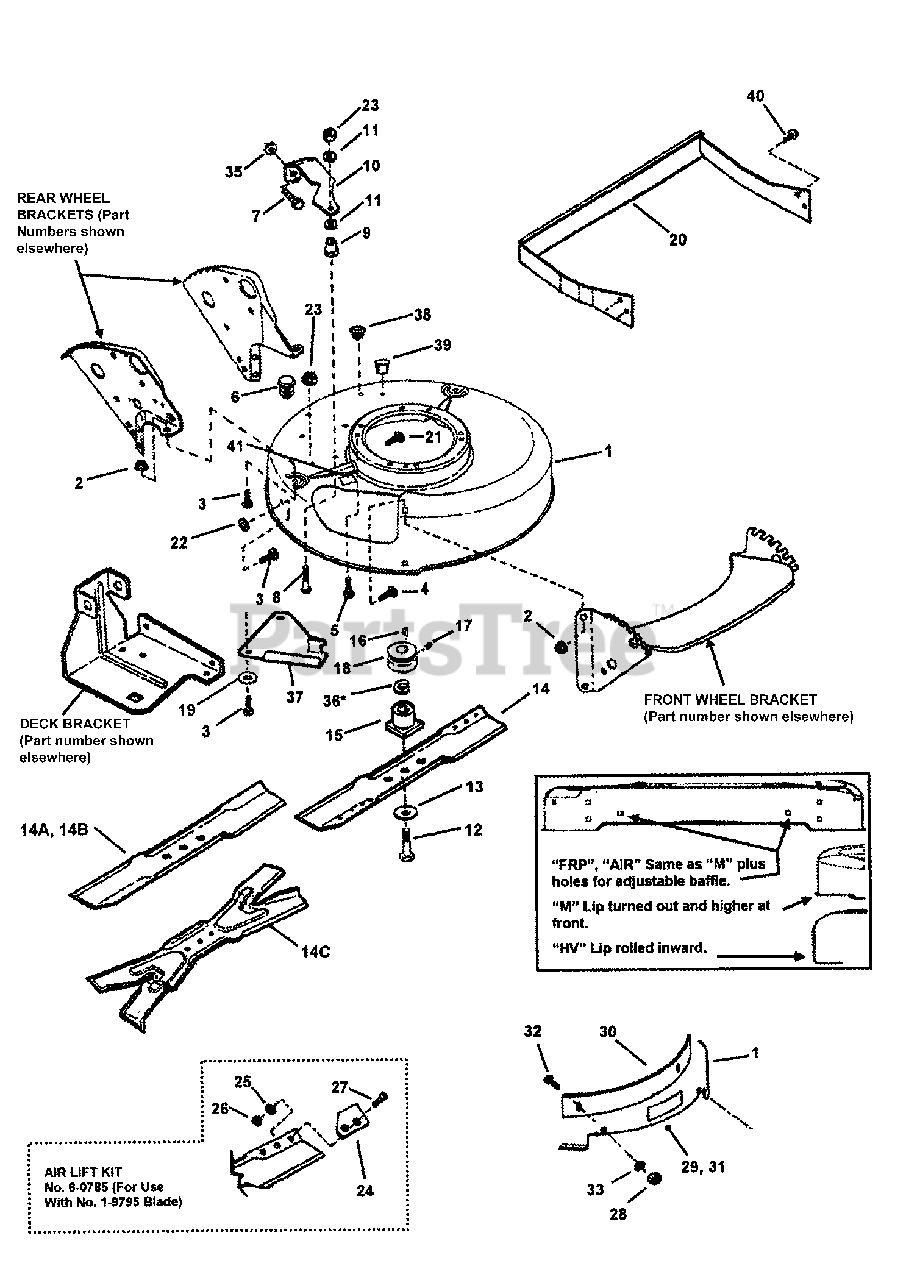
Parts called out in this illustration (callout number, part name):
1	DECK, 21" Mower ("HV" deck w/decals)
1	DECK, 21" Mower (Baffle Type deck w/decals)
1	DECK, 21" Mower ("M" deck w/decals)
1	DECK, 21" Mower (Swivvel wheel "M" deck w/o decals)
2	NUT, 5/16-18 Hex Flange Lock, GR5
3	BOLT, 5/16-18 x 1/2" Short Neck Carriage GR5
4	BOLT, 5/16-18 x 1-1/8" Short Neck Carriage GR5
5	SCREW, 3/8-16 x 1" Self-Tap
6	PLUG, Hole
7	SCREW, 5/16-18 x 1/2" Hex Head Cap, GR5
8	BOLT, 5/16-18 x 2-1/4" Hex Flange Lock
9	BUSHING
10	COVER, Belt
11	WASHER, 7/16" Flat
12	SCREW, 3/8-24 x 1-3/4 Hex Head Cap GR5
13	WASHER, 3/8" I.D. Cone
14	BLADE, Cutter (European)
14A	BLADE, Cutter (Mulching)
14B	BLADE, Cutter (Standard Lift)
14C	BLADE, 21" Ninja (Quad Edge)
15	HUB, Blade Drive 25mm
15	HUB, Blade Drive 7/8"
16	KEY, Woodruff # 605
16	KEY, Hi-Pro #HP506
16	KEY, Woodruff #505 Hi-Pro
17	SCREW, 5/16-18 x 5/16" Hex Socket Set
18	PULLEY, Engine (25mm I.D. x 2-1/8" O.D.)
18	PULLEY, Engine (7/8" I.D. x 2-1/8" O.D.)
19	WASHER, 7/16" Flat
20	WELDMENT, Fender
21	BOLT, 5/16-18 x 3/4" Short Neck Carriage GR5
22	RETAINER, 5/16" Bolt
23	NUT, 5/16-18 Hex Flange Lock, GR5
24	LIFT, Air
25	WASHER, 5/16" Internal Tooth Lock
26	NUT, 5/16-24 Hex, GR5
27	SCREW, 5/16-24 x 21/32" Machine
28	NUT, 5/16-18 Hex Center Lock
29	DECAL, Front Baffle
30	BAFFLE, Front
31	DECAL, Front Baffle
32	BOLT, 5/16-18 x 3/4" Carriage, GR5
33	WASHER, 5/16" Internal/External Tooth Lock
34	WINGNUT, 5/16-18 Nyloc
35	WASHER, 5/16" Flat
36	SPACER, 1/16" Thick, Blade Hub
37	BAFFLE, Belt
38	PLUG, 5/16" Square Hole
39	PLUG, 5/16" Round Hole
40	SCREW, 1/4-20 x 1/2" Hex Washer Self-Tap
41	DECAL, Warning Chute/Deflector
